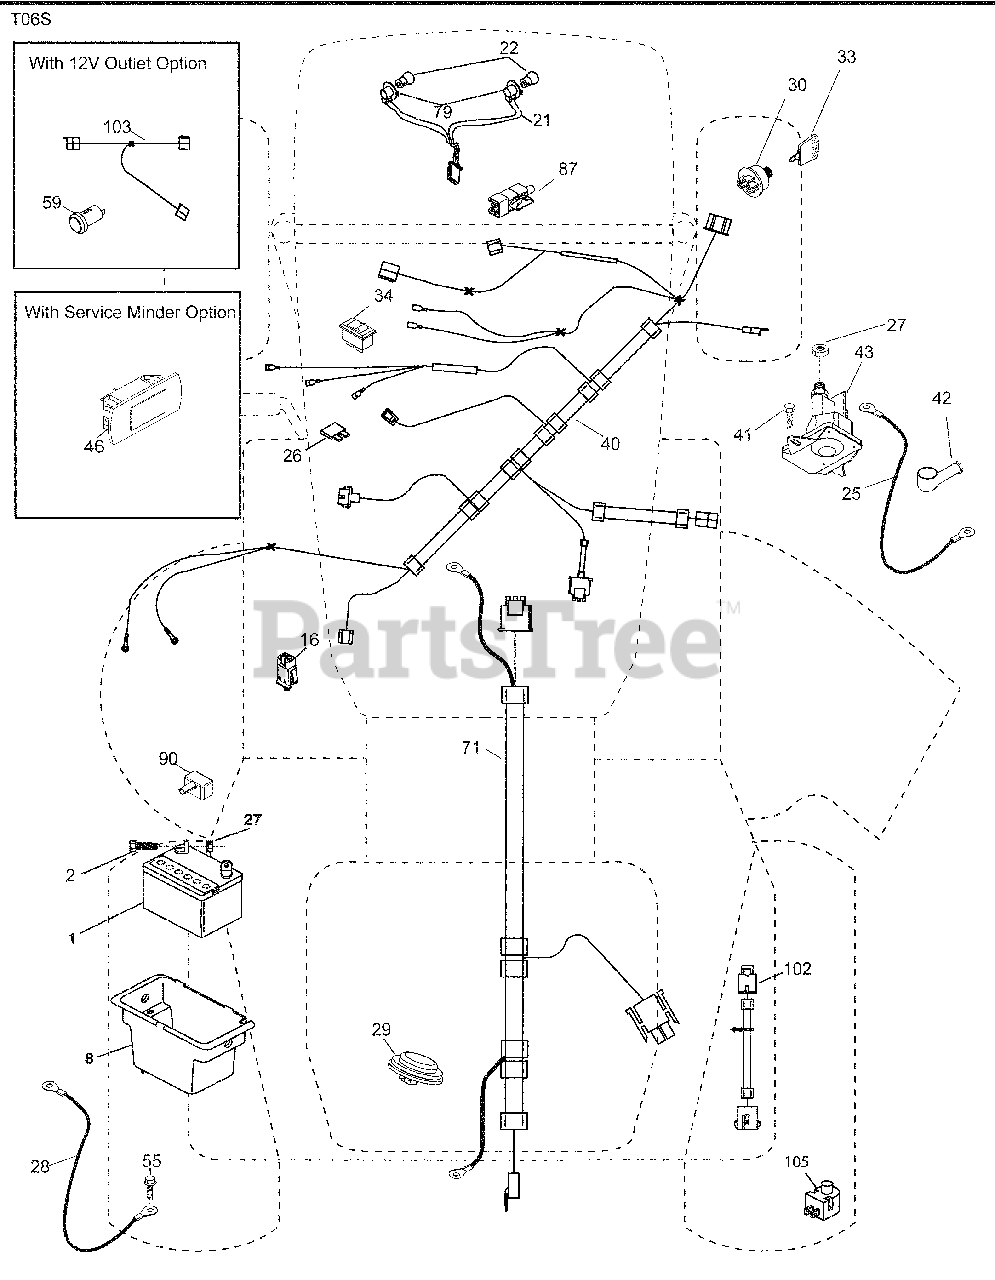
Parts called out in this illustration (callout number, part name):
1	Battery
2	Bolt Hex Head 1/4-20 x 3/4
8	Box Battery
16	Switch Interlock Push-In
21	Harness Socket Light w/4152J
22	Bulb Light
25	Cable Starter
27	Nut Keps Hex 1/4-20 unc
28	Cable, Ground
29	Switch, Seat
30	Switch, Ign
33	Key/Chain
34	Switch Light/Reset
40	Harness Ign. Dash
41	Screw Thd Cut 1/4-20 x 1/2
42	Cover, Terminal
43	Solenoid
46	Gauge Serviceminder Hrmtr
55	Screw Thdrol 5/16-18 x 3/4 TYTT
71	Harness Ign.
79	Socket Asm. Bulb
87	Switch Interlock
90	Cover Terminal
102	Harness Pigtail
105	Switch Reverse
